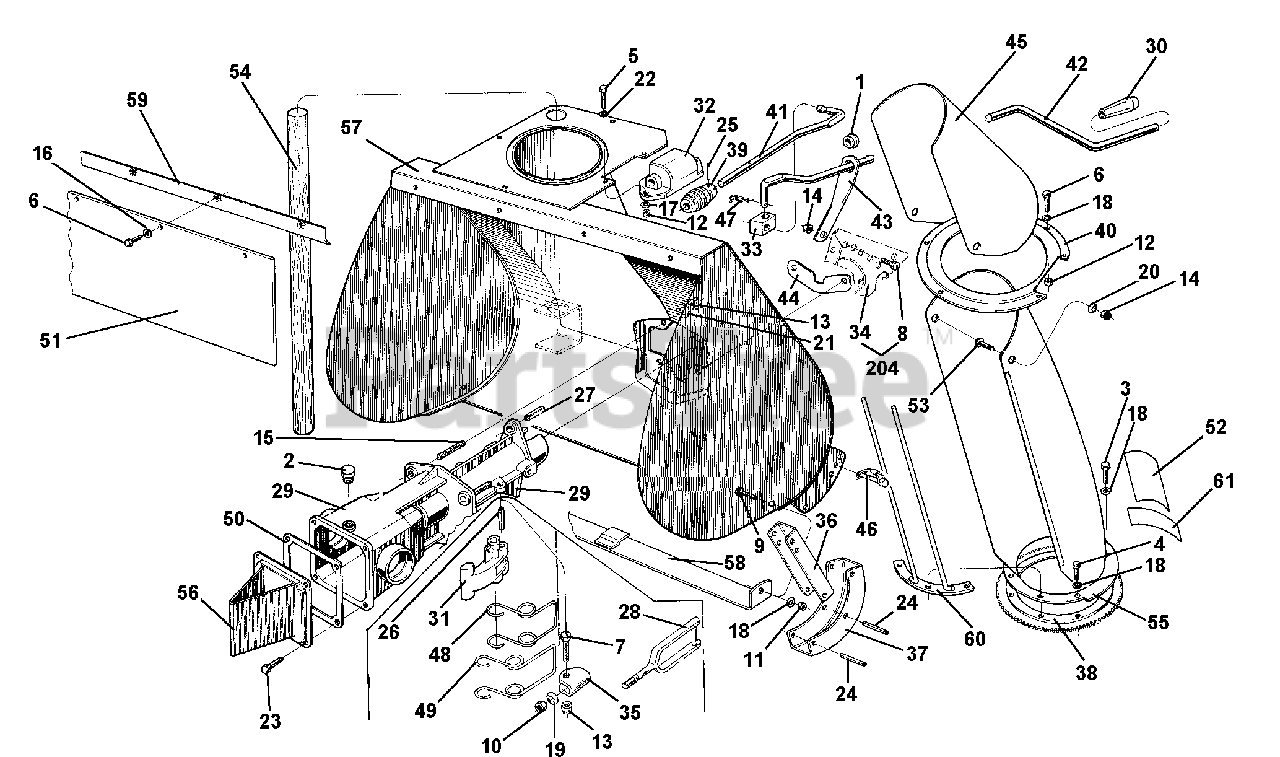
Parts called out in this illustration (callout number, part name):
2	PLUG 1/4 GAS
3	SCREW TE M6 X 10 UNI 5739-5S
4	SCREW TE M6 X 14
5	SCREW M6 X 25
6	SCREW TE M6 X 16
7	SCREW TE M8 X 30
8	SCREW TE M10 X 20 UNI 5739-8G
9	SCREW M6 X 16
11	NUT, SELF LOCKING M6
12	SELF LOCKING NUT M6
13	NUT, SELF LOCKING M8
14	NUT, SELF LOCKING M10
15	STUD M8 X 32 X 14 X 14
16	WASHER, FLAT 6.4
17	FLAT WASHER
18	SUPER WASHER 6 DIN 6796
19	SUPER WASHER 8 DIN 6796
20	SUPER WASHER 10 DIN 6796
21	WASHER, LOCK 8.4
22	WASHER, LOCK 6.4
23	SCREW M6 X 12
24	PIN, LOCKING 6 X 50
25	PIN, LOCKING SW 3 X 22 SPIRAL
26	SPIRAL PIN 8 X 40
27	LOCKING PIN 12 X 26
29	SNOW THROWER SUPPORT
32	SCREW SUPPORT
34	HANDLEBAR SUPPORT
35	IMPLEMENT HOOK COUPLING
41	ROD EXTENSION
42	FUNNEL CONTROL ROD
44	CLOSING PLATE
49	LONG SPRING HOOK
52	FUNNEL STICKER
53	SCREW M10 X 25
57	SNOW THROWER CRANKCASE
58	BLADE 50 CM
59	MUDFLAP STOP
60	FUNNEL GRATE
61	STICKER "MADE IN ITALY"
